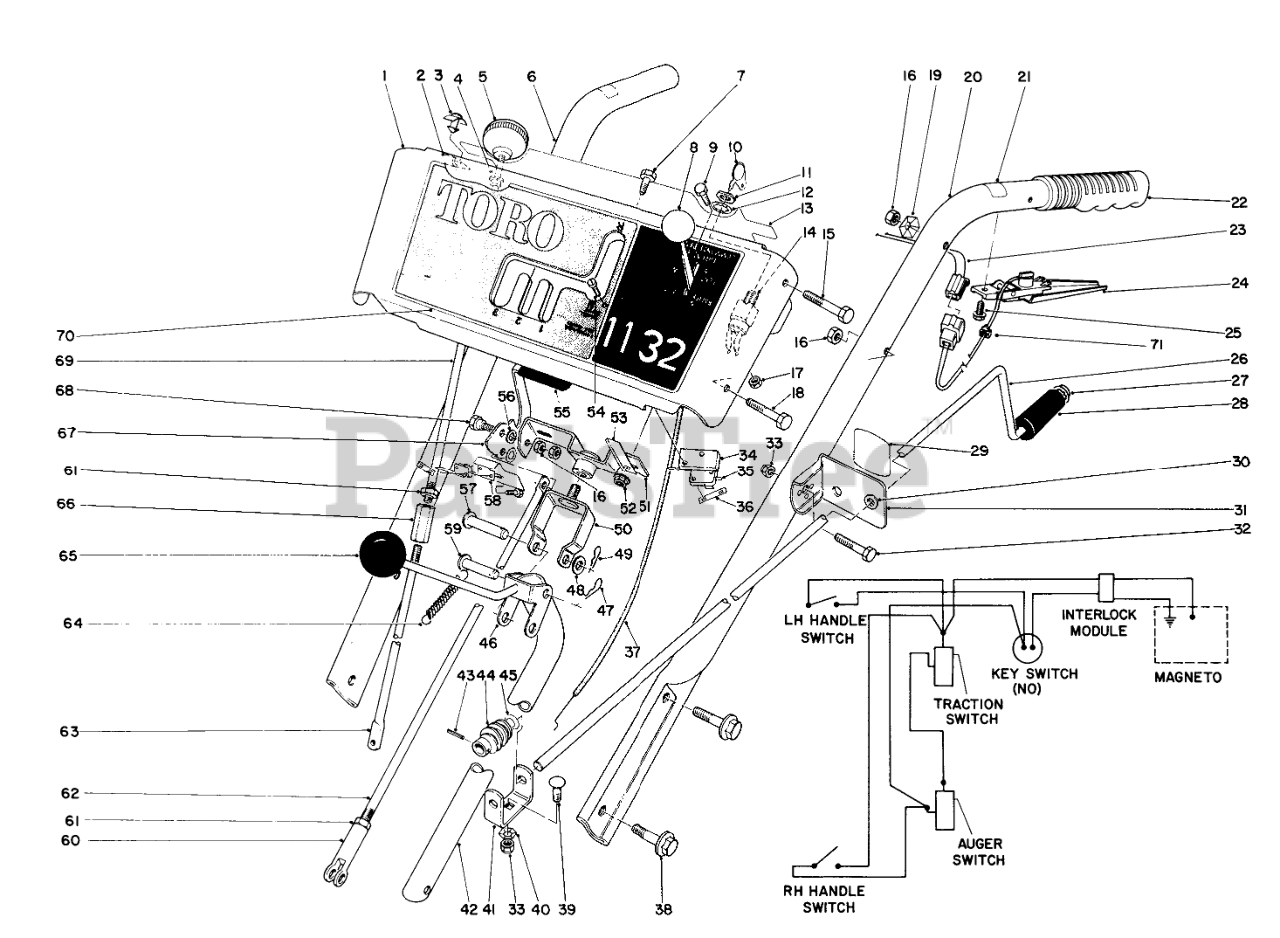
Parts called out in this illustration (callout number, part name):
1	Escutcheon Plate (Incl. Ref. #13 & 70)
2	WIRE CLAMP
3	Mounting Stud
4	NYLINER #6LI-FF TYPE 7
5	KNOB-LEVER
6	Handle Right
7	SCREW-HH
8	CONTROL KNOB
9	HEX HEAD SEMS 10-24X1/2
10	Key
12	WASHER-TOOTH, INTERNAL
13	BACK ESCUTCH DECAL
14	Key Switch (Incl. Ref. #11 &12)
15	SCREW-HH
16	NUT-LOCK, CONE
17	NUT-LOCK, NI
18	SCREW-HH
19	Washer
20	HANDLE LEFT
21	INTERLOCK DECAL
22	Grip Handle
23	Wire Harness (Incl. Ref. #71)
24	INTERLOCK HDLE SWITCH
25	SCREW
26	Chute Control Rod
27	RETAINER-PUSH ON
28	GRIP-CONTROL, CHUTE
29	CHUTE DECAL
30	Bushing
31	Bracket-Chute Control Mtg. (Incl. Ref. #29 & 30)
32	SCREW-HH
33	NUT-LOCK, NI
34	SWITCH MTG PAD
35	SWITCH-MICRO
36	NUT-SPEED
37	Throttle Contrl
38	SCREW-HHF
39	BOLT-CARR
40	WASHER-LOCK
41	WORM BRACKET
42	Rod Traction Shift
43	PIN-SPRING
44	GEAR-WORM, CHUTE
45	WASHER-SPRING
46	SHIFT ROD WA
47	PIN-COTTER
48	WASHER-FLAT
49	PIN-HAIR
50	PIVOT BRKT WA
51	SWIVEL BLOCK WA
52	NUT-LOCK, HHF
53	Retainer Wire
54	SCREW-SPH
55	AUGER CLUTCH HND GRIP
56	WASHER-PLAIN
57	PIN-CLEVIS
58	SWITCH BRKT
59	PIN-CLEVIS
60	CLEVIS
61	NUT-HJ
62	DRAG LINK
63	LOWER WHL CLUTCH ROD
64	CONT ROD SPRING 0
66	WHL ROD COUPLING
67	Auger Clutch Handle
68	SCREW-SHOULDER
69	UP WHEEL CLUTCH ROD
70	ESCUTCHEON DECAL
71	Mount-Wire
